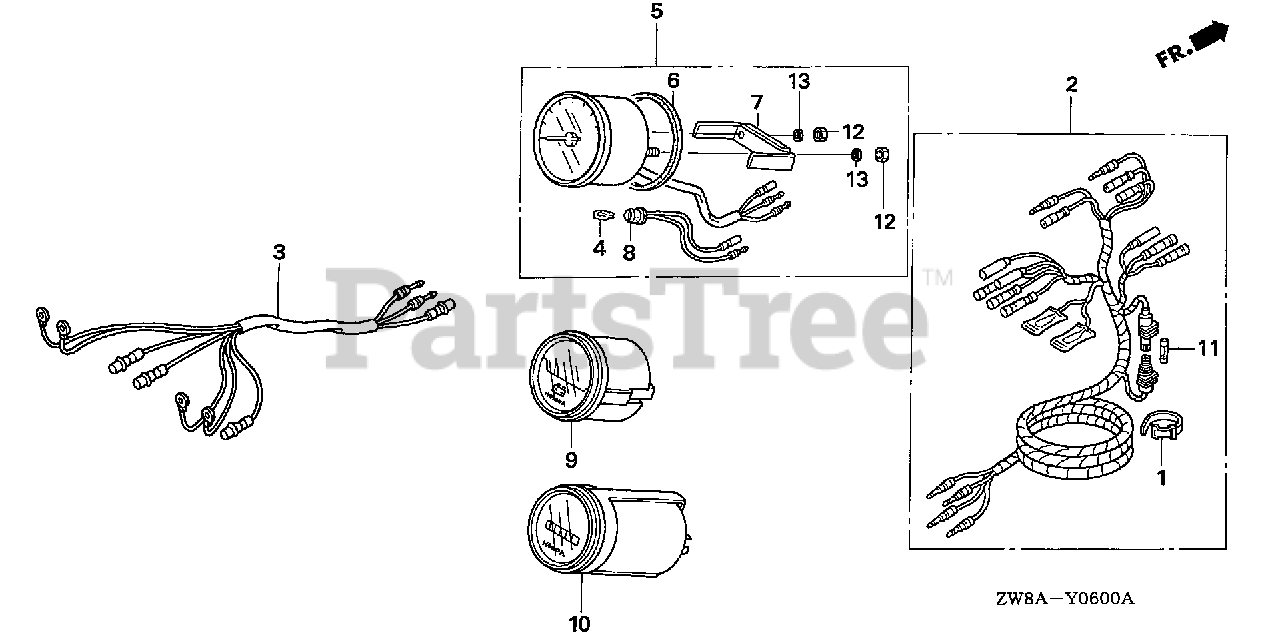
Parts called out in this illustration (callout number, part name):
1	BAND B1, WIRE
2	HARNESS ASSY., METER (A)
3	HARNESS ASSY., METER (B)
4	BULB, WEDGE BASE (T10) (12V 1.7W) (STANLEY)
5	TACHOMETER ASSY.
6	GASKET
7	BRACKET
8	SOCKET
9	METER ASSY., VOLT
10	METER ASSY., HOUR L.C.D.
11	FUSE A (10A)
12	NUT, HEX. (5MM)
13	WASHER, SPRING (5MM)
